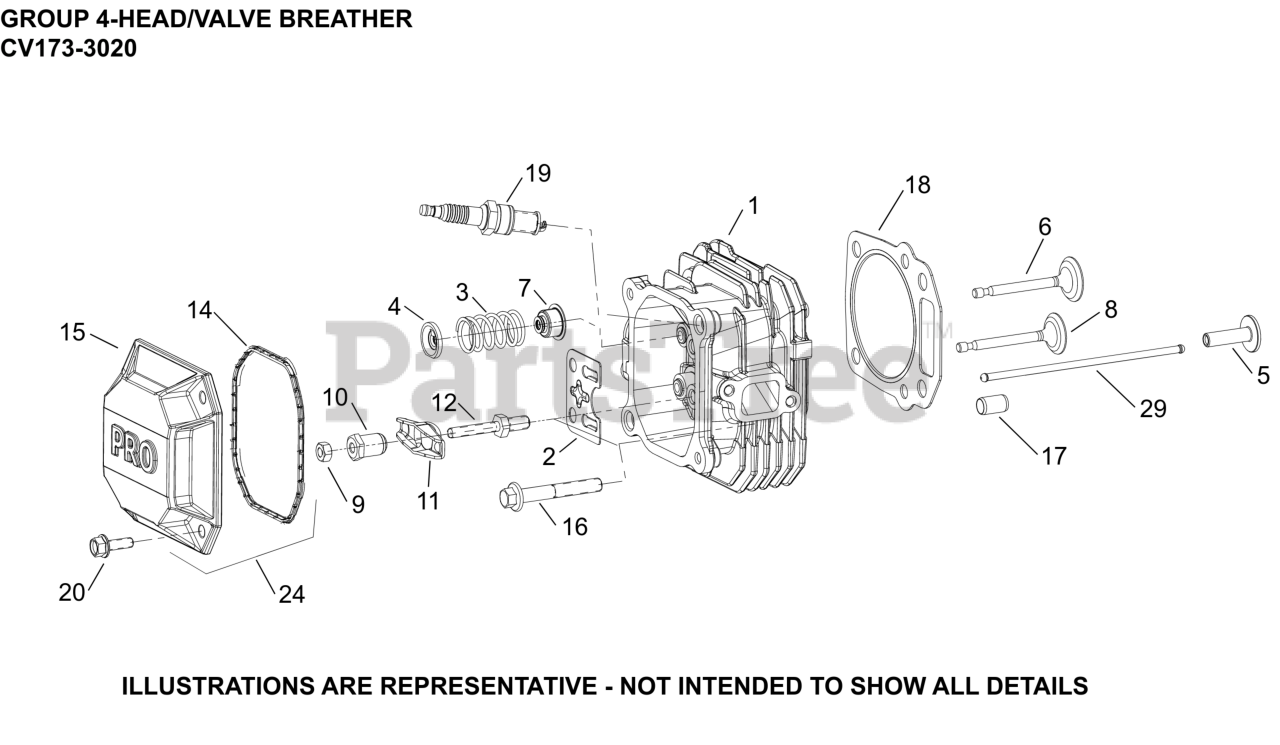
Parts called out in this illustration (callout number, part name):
1	HEAD, CYLINDER
2	PLATE, PUSHROD GUIDE
3	SPRING, VALVE
4	RETAINER, VALVE SPRING
5	LIFTER, VALVE
6	VALVE, INTAKE
7	SEAL, VALVE
8	VALVE, EXHAUST
9	NUT, HEX JAM
10	PIVOT, ROCKER ARM
11	ARM, ROCKER
12	STUD, ROCKER ARM
14	SEAL, VALVE COVER
15	COVER, VALVE-USE 14 096 184-S
16	SCREW, HEX FLANGE M8
17	DOWEL, CYLINDER HEAD
18	KIT, HEAD GASKET (CV173)
18	KIT, HEAD GASKET
19	PLUG, SPARK 12MM RFI
20	SCREW, HEX FLANGE (M6)
24	COVER, VALVE ASSEMBLY
29	ROD, PUSH
